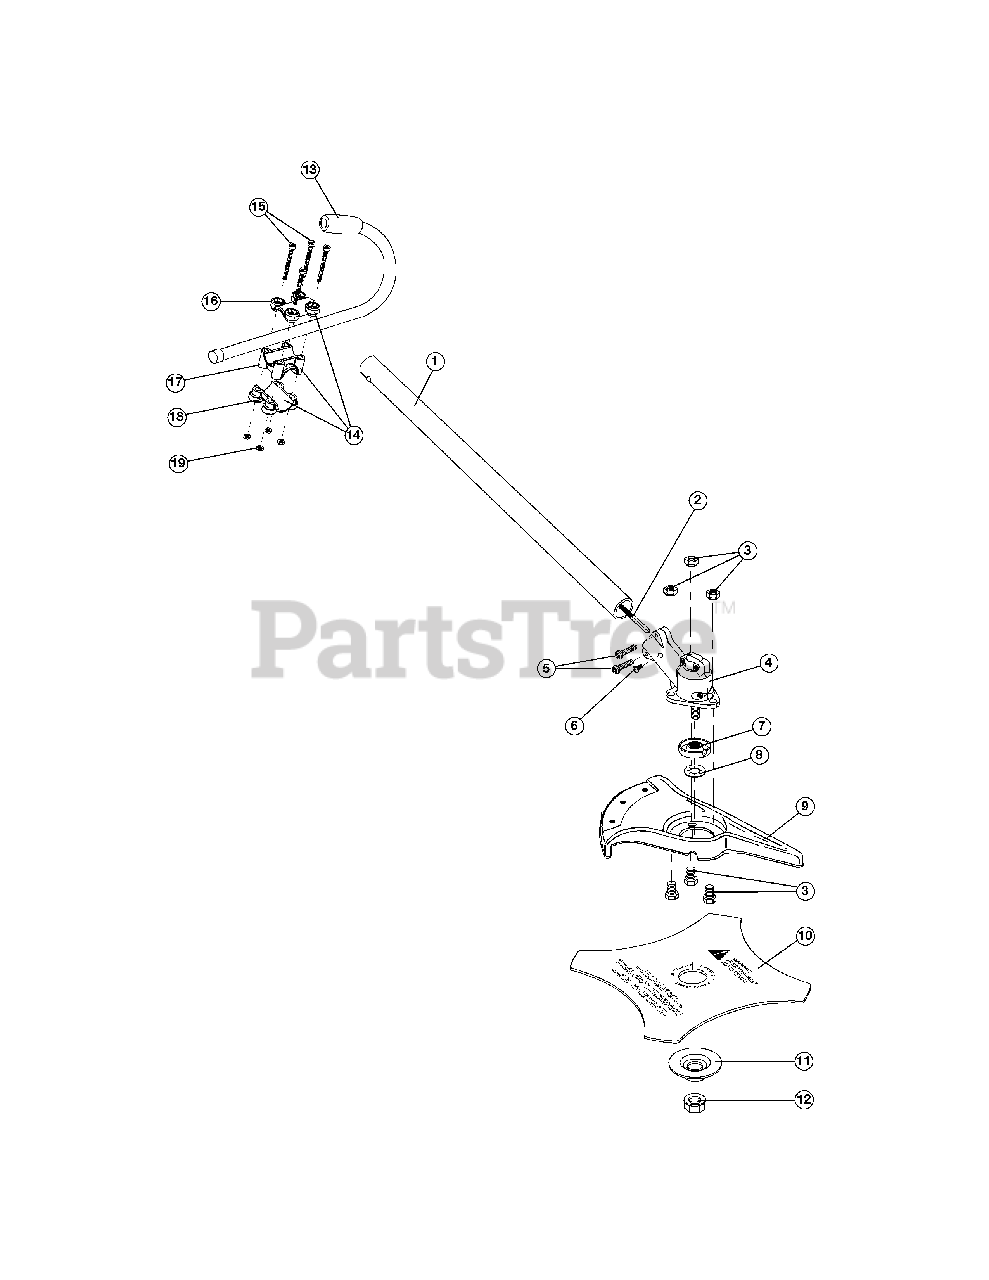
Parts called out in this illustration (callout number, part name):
1	Lower Drive Shaft Housing Assembly
2	Lower Flexible Drive Shaft
3	Shield Mount Screw Assembly
4	2 piece Gearbox Assembly (Incl. Ref No. 5-6)
5	Gearbox Mounting Hardware
6	Anti-Rotation Screw
7	Blade Driver
8	Palnut
9	Blade Shield/Shield Mount
10	4-Tooth Blade
11	Retaining Washer
13	J-Handle Assembly
14	Handle Bracket Assembly (Incl. Ref No. 15-18)
16	Upper Handle Clamp
17	Middle Handle Clamp
18	Lower Handle Clamp
